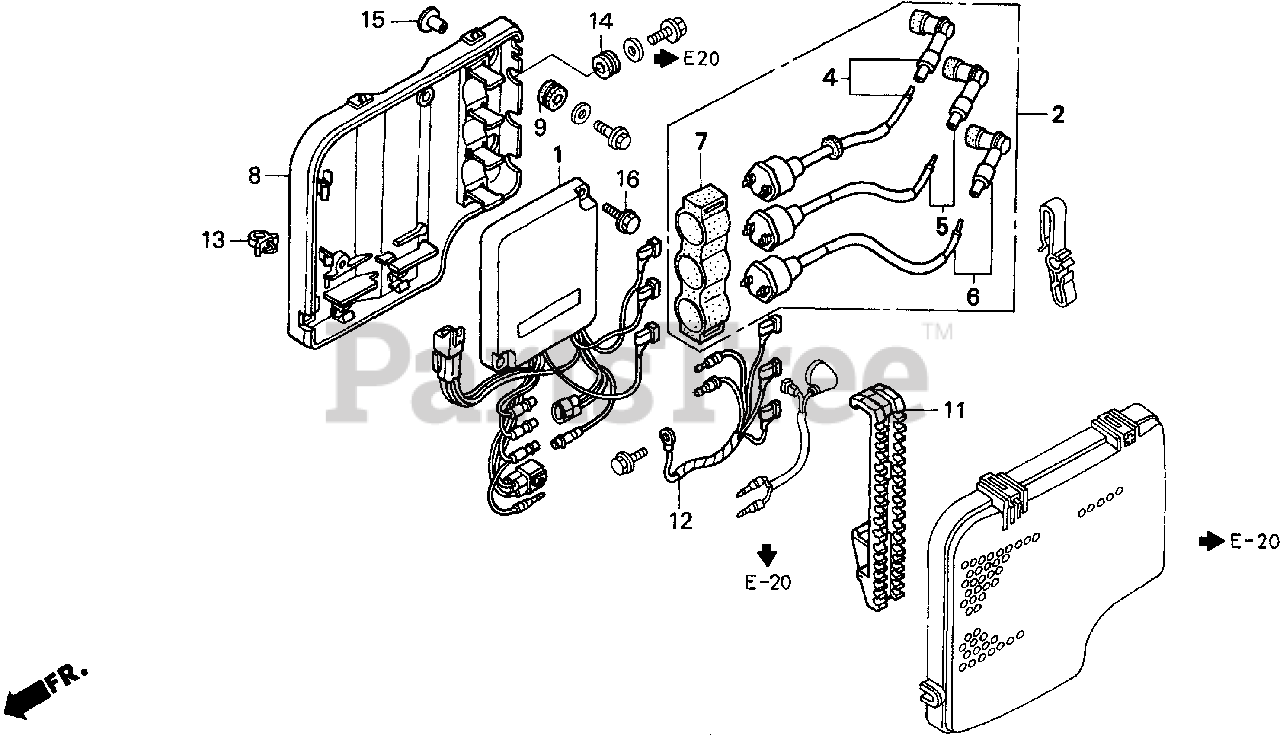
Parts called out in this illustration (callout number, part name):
1	MODULE ASSY., IGNITION CONTROL (CDI)
2	COIL ASSY., IGNITION
4	COIL, IGNITION (1)
5	COIL, IGNITION (2)
6	COIL, IGNITION (3)
7	SUSPENSION, IGNITION COIL
8	CASE, IGNITION CONTROL MODULE
9	GROMMET, IGNITION CONTROL MODULE CASE (B)
11	BRACKET, CONNECTOR (A)
12	WIRE ASSY., GROUND
13	CLIP, TURN SIGNAL WIRE
14	GROMMET, CASE (LOWER)
15	COLLAR, IGNITION CONTROL MODULE CASE
15	COLLAR, MODULE IGNITION CONTROL CASE (CDI)
16	BOLT, FLANGE (6X20)
